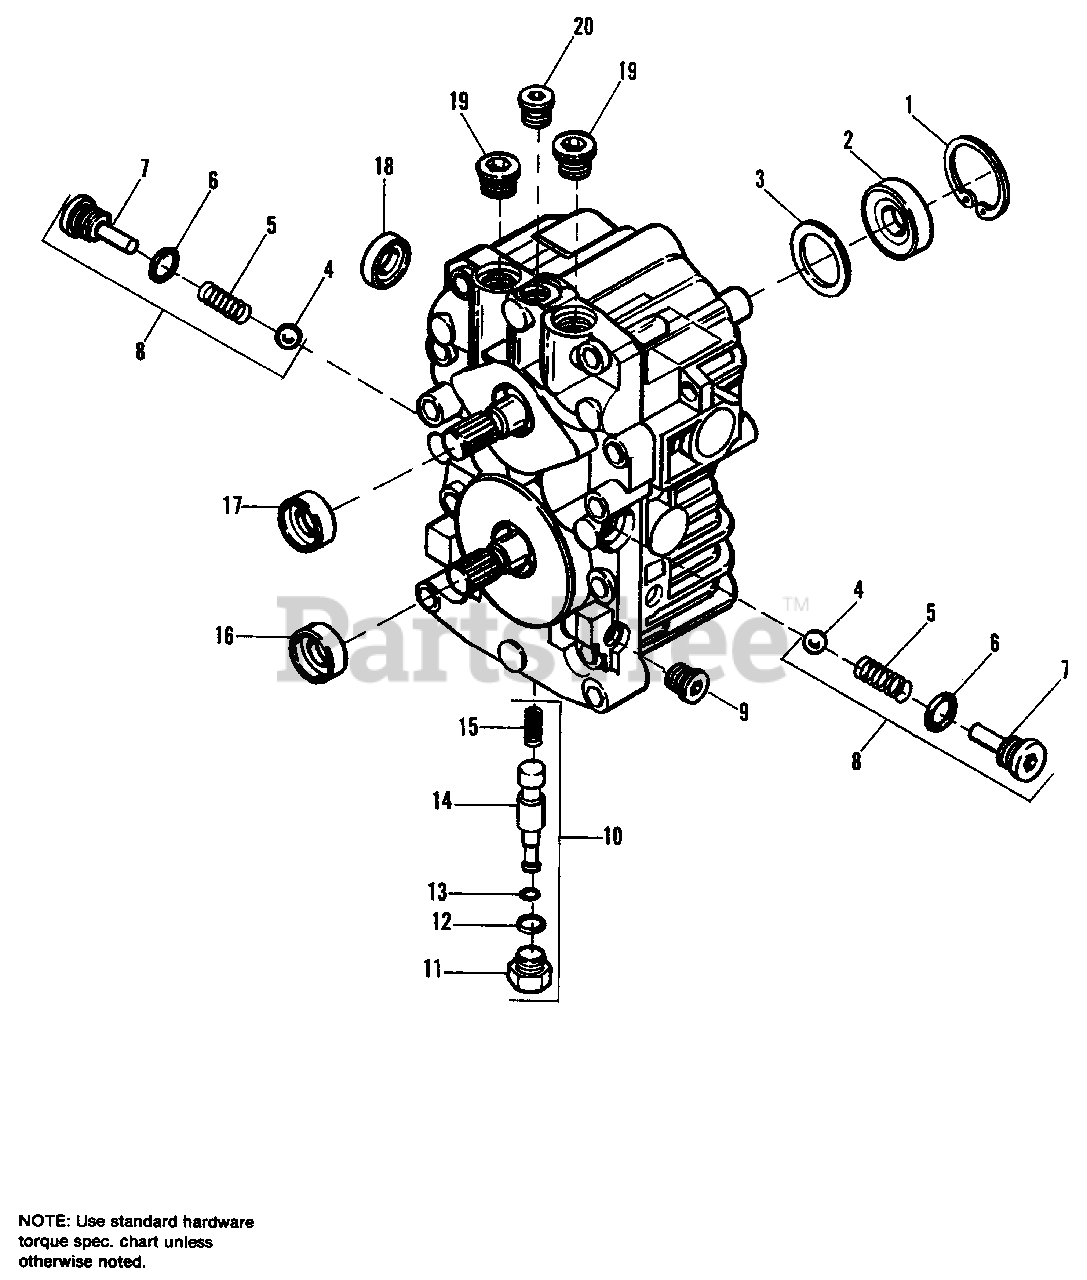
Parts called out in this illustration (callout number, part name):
1	RETAINING RING
2	LIP SEAL
3	SPACER
6	O-RING (.078 x .468)
7	CHECK VALVE PLUG
8	CHECK VALVE KIT (Incl. Ref. Nos. 4-7)
10	BY PASS VALVE KIT (Incl. Ref. Nos. 11-15)
11	BY PASS PLUG
12	O-RING (.072 x .351)
13	O-RING
14	BY PASS SPOOL
16	LIP SEAL, Motor
17	LIP SEAL, Pump
18	LIP SEAL
19	O-RING BOSS PLUG, 9/16-18 Str. Thd., Socket Hd.
20	O-RING BOSS PLUG, 7/16-20 Str. Thd., Socket Hd.
